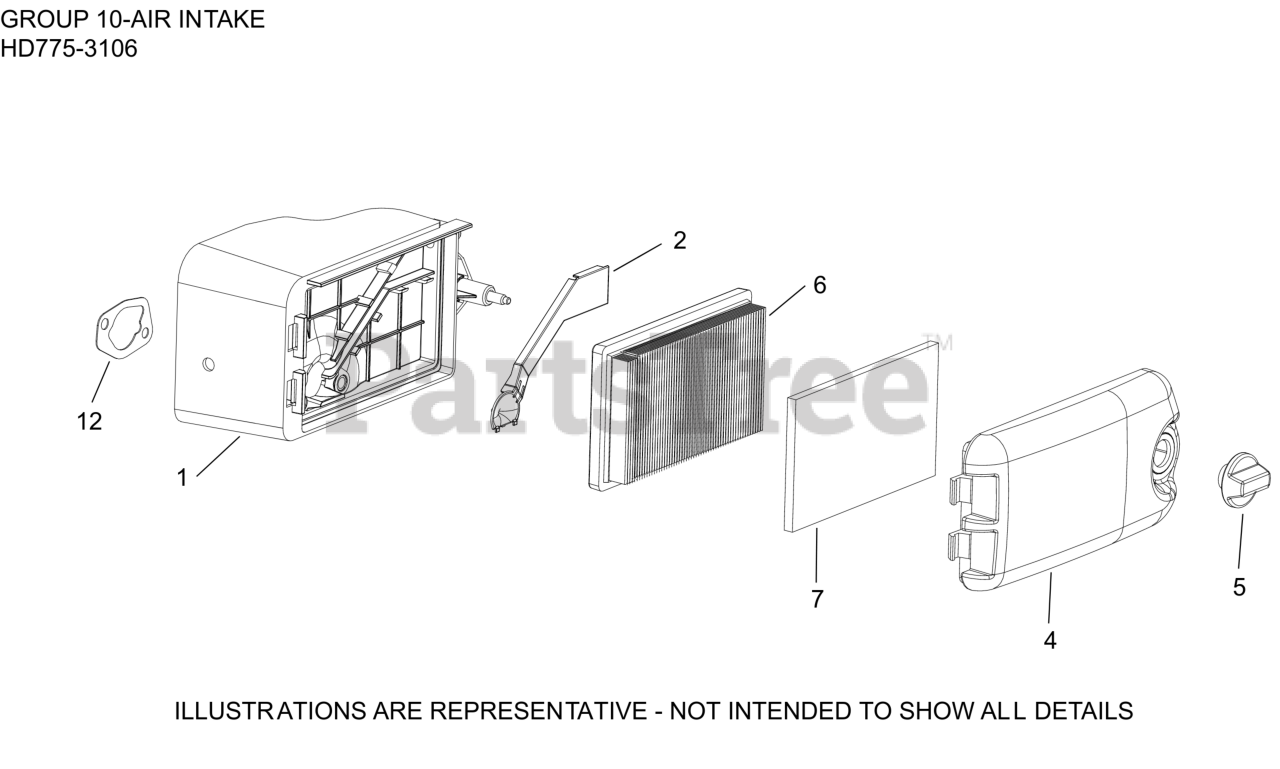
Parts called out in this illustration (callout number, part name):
1	KIT, AIR CLEANER BASE
2	COVER, A/C BASE (BREATHER GAS)
4	COVER, AIR CLEANER
5	KNOB-USE 14 341 07-S
6	ELEMENT, AIR FILTER
7	ELEMENT, PRE-CLEANER
12	GASKET, AIR CLEANER BASE
